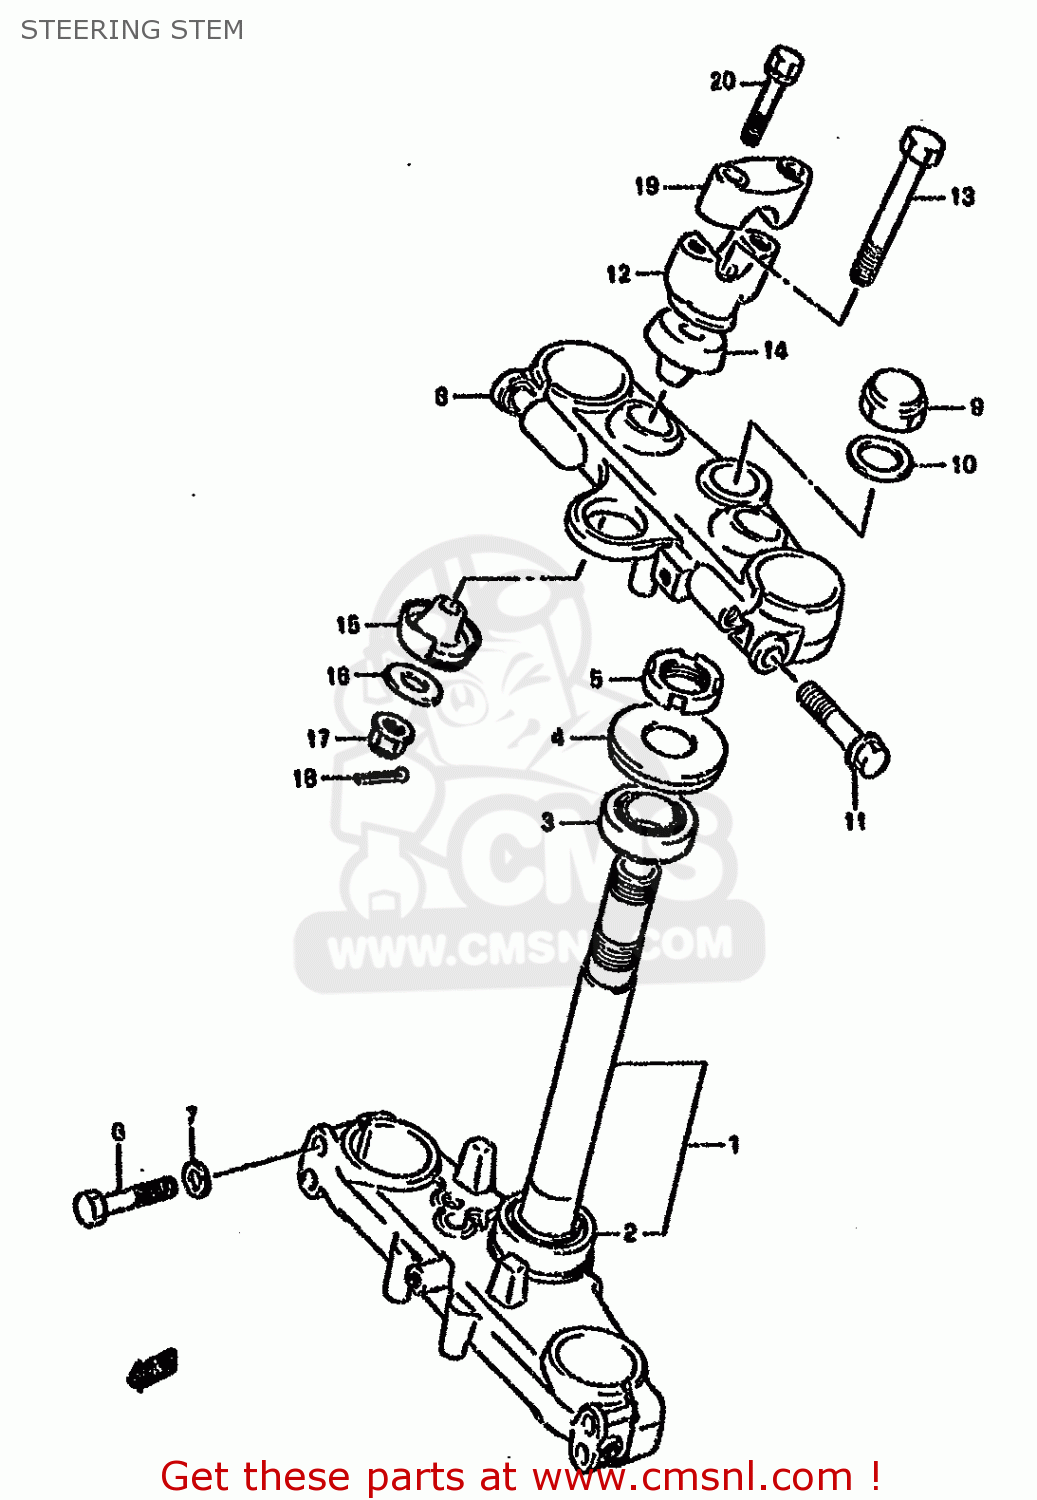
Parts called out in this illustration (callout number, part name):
1	STEM,STEERING
2	BEARING(30X55X17)
3	TAPER,ROLLER BEARING
4	SEAL,STEERING UPR DUST
5	NUT,STEERING STEM
6	BOLT
7	LOCK WASHER
8	BRACKET,UPPER
9	NUT,CAP
10	WASHER(22.5X32X1.6)
11	BOLT
12	HOLDER,HANDLE LWR
13	BOLT
14	DAMPER,UPR
15	DAMPER,LWR
16	WASHER,HANDLEBAR HOLDER
17	NUT
18	COTTER PIN
19	HOLDER,HANDLE UPR
20	BOLT
